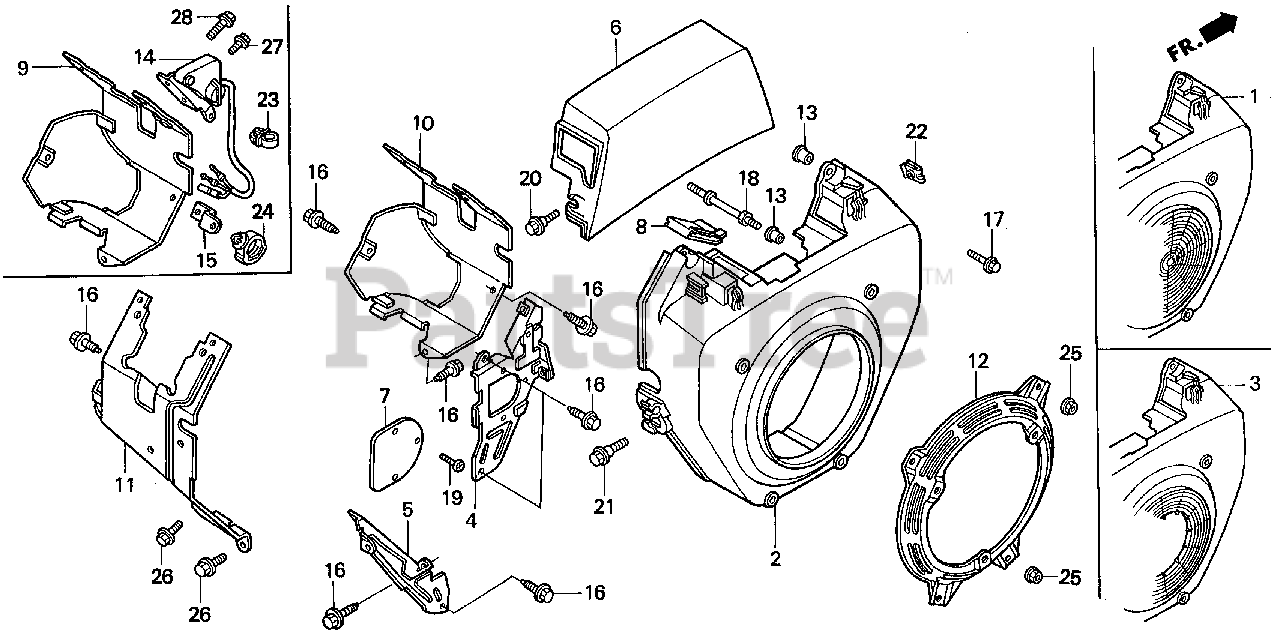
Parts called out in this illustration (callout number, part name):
1	COVER, FAN *R8* (BRIGHT RED)
4	PLATE, R. SIDE
5	PLATE, L. SIDE
6	HOOD, FAN COVER
8	PLUG, FAN COVER HOLE
10	SHROUD, R.
11	SHROUD, L.
13	COLLAR B, TAILLIGHT
16	BOLT, FLANGE (6X12) (CT200)
17	BOLT, FLANGE (6X23)
18	BOLT, STUD (6X75)
20	BOLT, FLANGE (6X20)
21	BOLT, FLANGE (6MM) (BLACK)
22	NUT, SPRING (6MM)
25	NUT, FLANGE (6MM)
26	BOLT, FLANGE (6X8)
